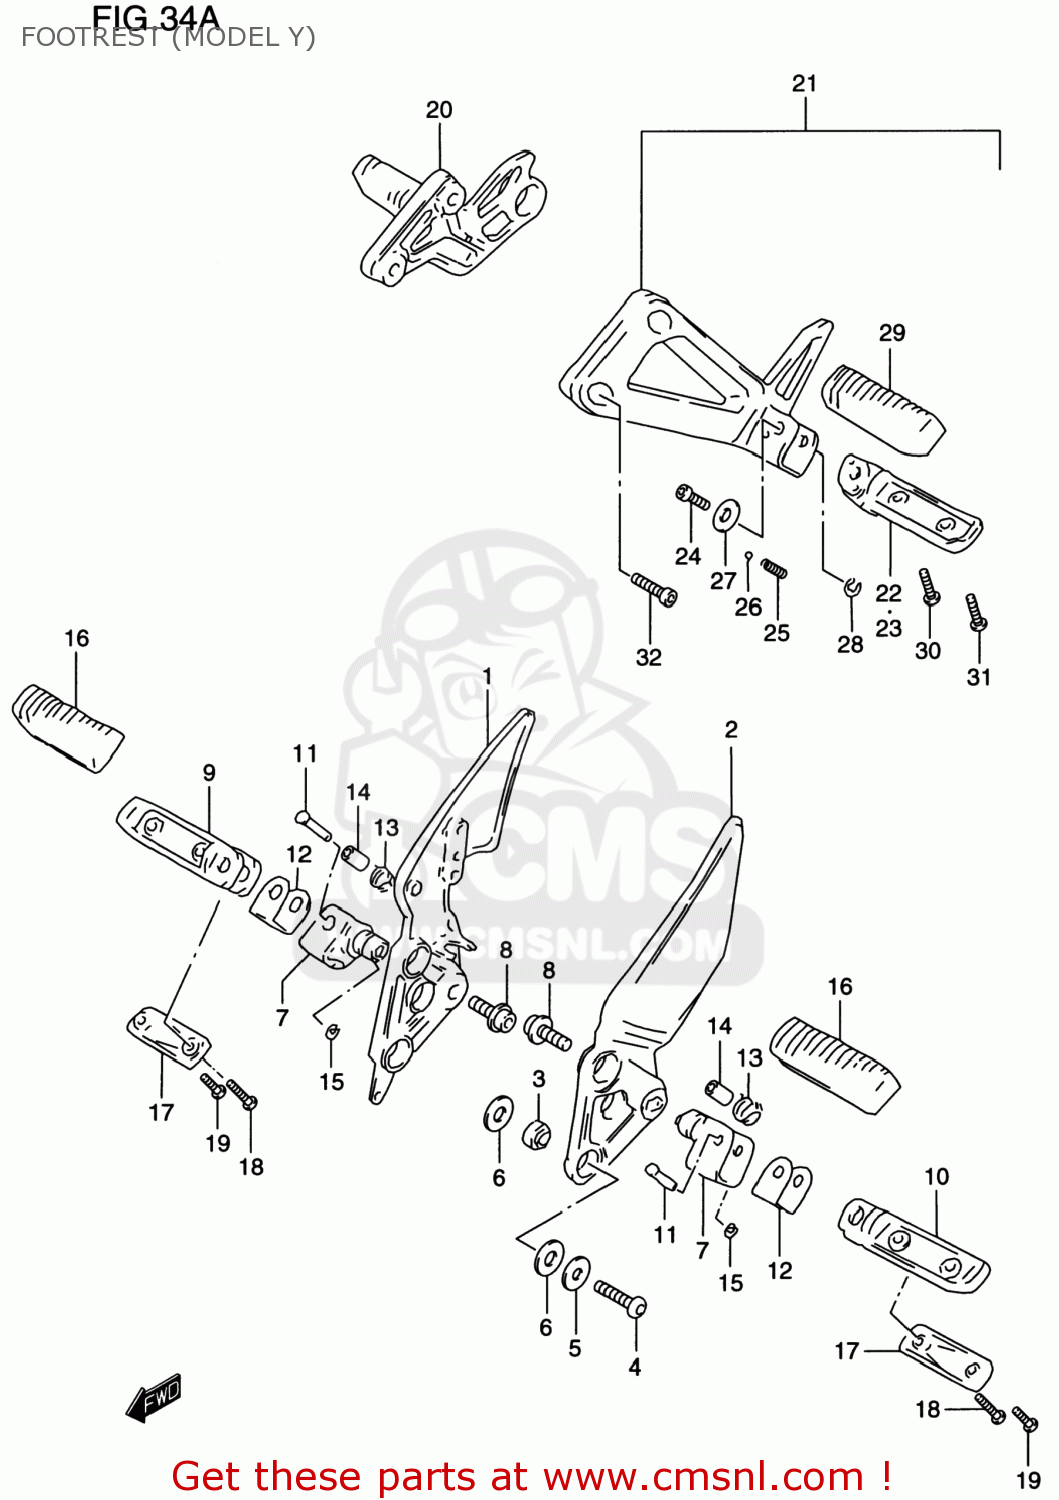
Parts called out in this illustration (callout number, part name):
1	BRACKET SET,FR FOOTREST,R
2	BRACKET SET,FR FOOTREST,L
3	BUSH(12X20X16)
4	BOLT(8X28)
5	WASHER (8.5X24X1.6)
6	WASHER(12.6X24X1.9)
7	HOLDER,FOOTREST
8	BOLT(10X28)
9	BAR,FOOTREST,R
10	BAR,FOOTREST,L
11	PIN(8X33.2)
12	CUSHION,FR FOOTREST
13	SPRING
14	SPACER(8.1X12X22)
15	E.RING
16	RUBBER,FOOTREST
17	BALANCER,FR FOOTREST LWR
18	SCREW
19	SCREW
20	FOOTREST ASSY,PILLION,R
21	FOOTREST ASSY,PILLION,L
22	BAR,PILLION FOOTREST,R
23	BAR,PILLION FOOTREST,L
24	BOLT,PILLION FOOTREST
25	SPRING
26	BALL
27	WASHER(10.5X24X1.6)
28	E.RING
29	RUBBER,FOOTREST
30	SCREW 5X20
31	SCREW
32	BOLT(8X25)
